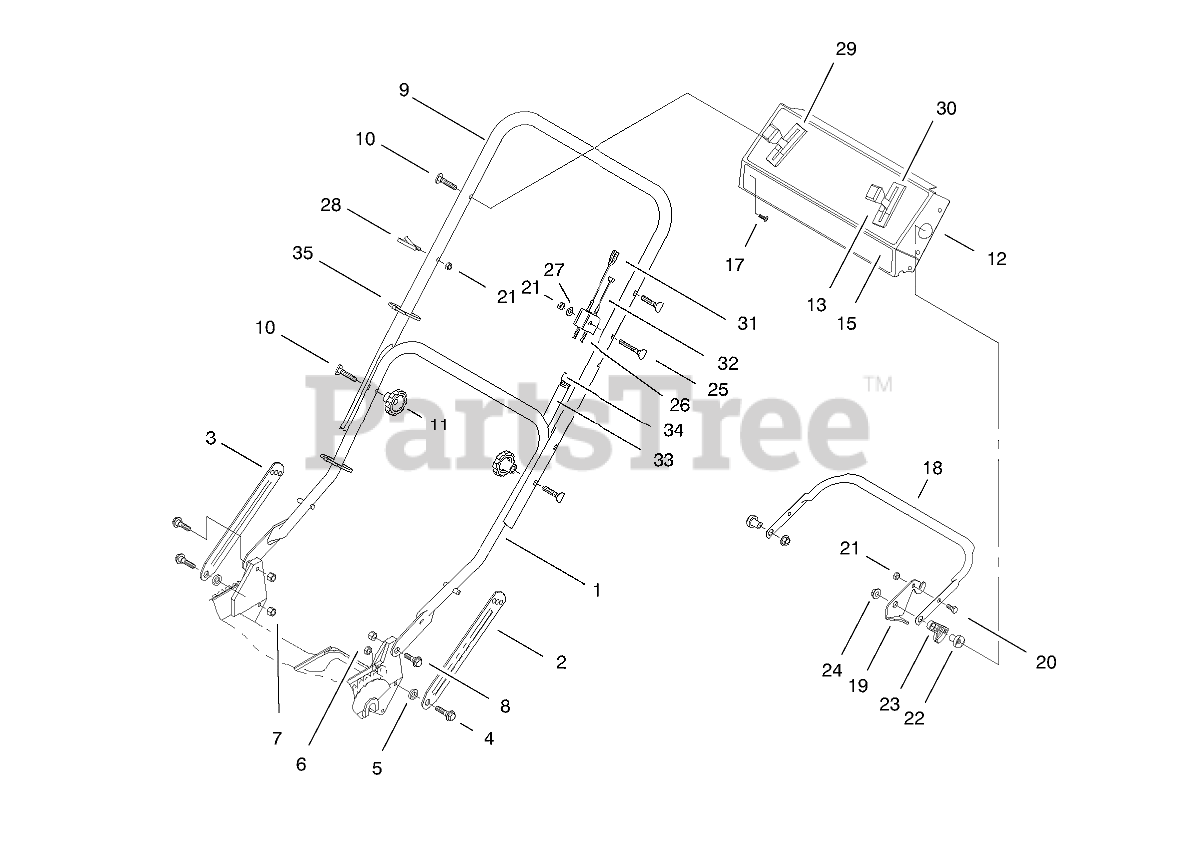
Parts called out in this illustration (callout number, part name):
1	ASM-Handle
2	Latch-Handle
3	Latch-Handle
4	SCREW-SHOULDER
5	SPACER
6	NUT-LOCK, NI
7	NUT-LOCK, NI
8	SCREW-SHOULDER
9	UPPER HANDLE (BLACK-TEX)
10	SCREW-HANDLE
12	Wa-Panel (Incl. Ref. #13)
13	DECAL - INSTRUCTION
15	DECAL - CONSOLE
17	SCREW-TAP
18	CONTROL BAR (BLACK-TEX)
19	Lever-Control
20	SCREW-HH
21	NUT-LOCK, NI
22	SPACER-SUPPORT
23	LEVER-TRACTION
24	NUT-LOCK NI
25	SCREW-HANDLE
26	SUPPORT-CABLE
27	WASHER-FLAT
28	GUIDE-ROPE
29	CONTROL-SPEED, GROUND
30	CABLE - THROTTLE
31	CABLE - BRAKE
32	CABLE-TRACTION
33	CONTROL CABLE COVER
34	FITTING-RING
35	TIE-CABLE
